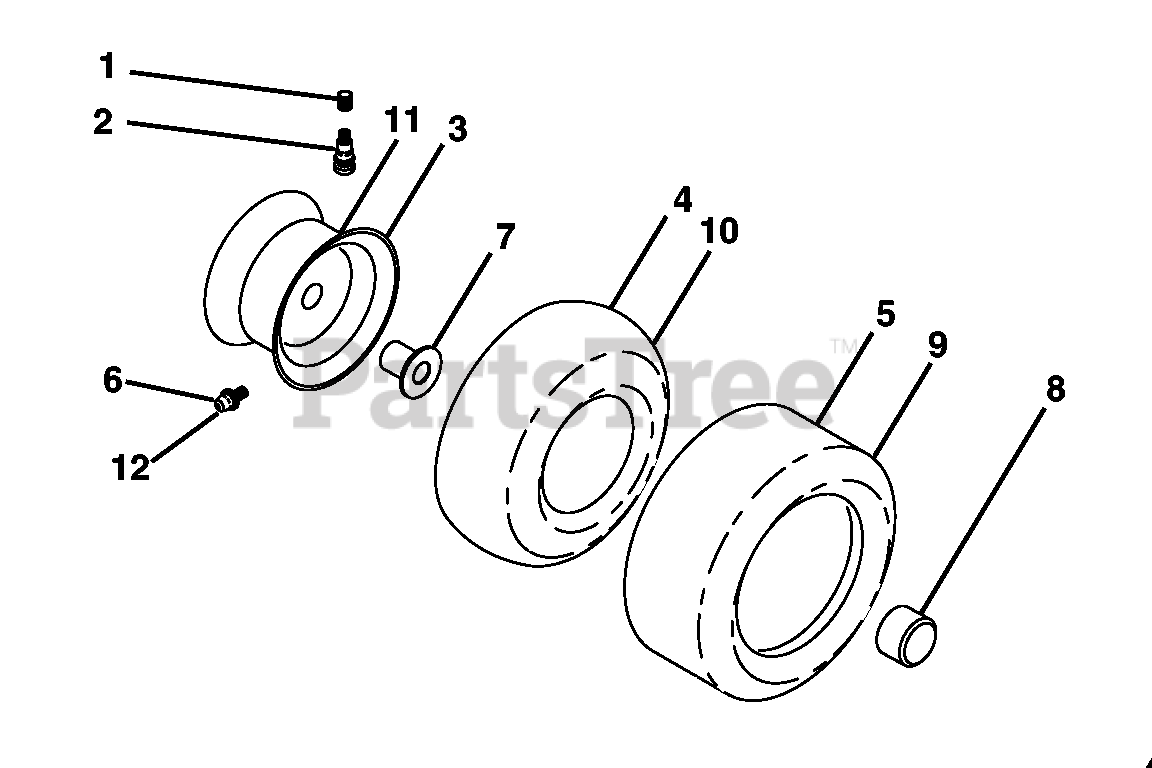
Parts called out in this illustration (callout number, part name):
1	Cap, Valve, Tire
2	Stem, Valve
3	Rim Assembly, Front
4	Tube, Front (Service Item Only)
5	Tire, Front
6	Fitting, Grease
7	Bearing, Flange (Front Wheel Only)
8	Cap, Hub
9	Tire, Rear
10	Tube, Rear (Service Item Only)
11	Rim Assembly, Rear
12	Fitting, Grease
